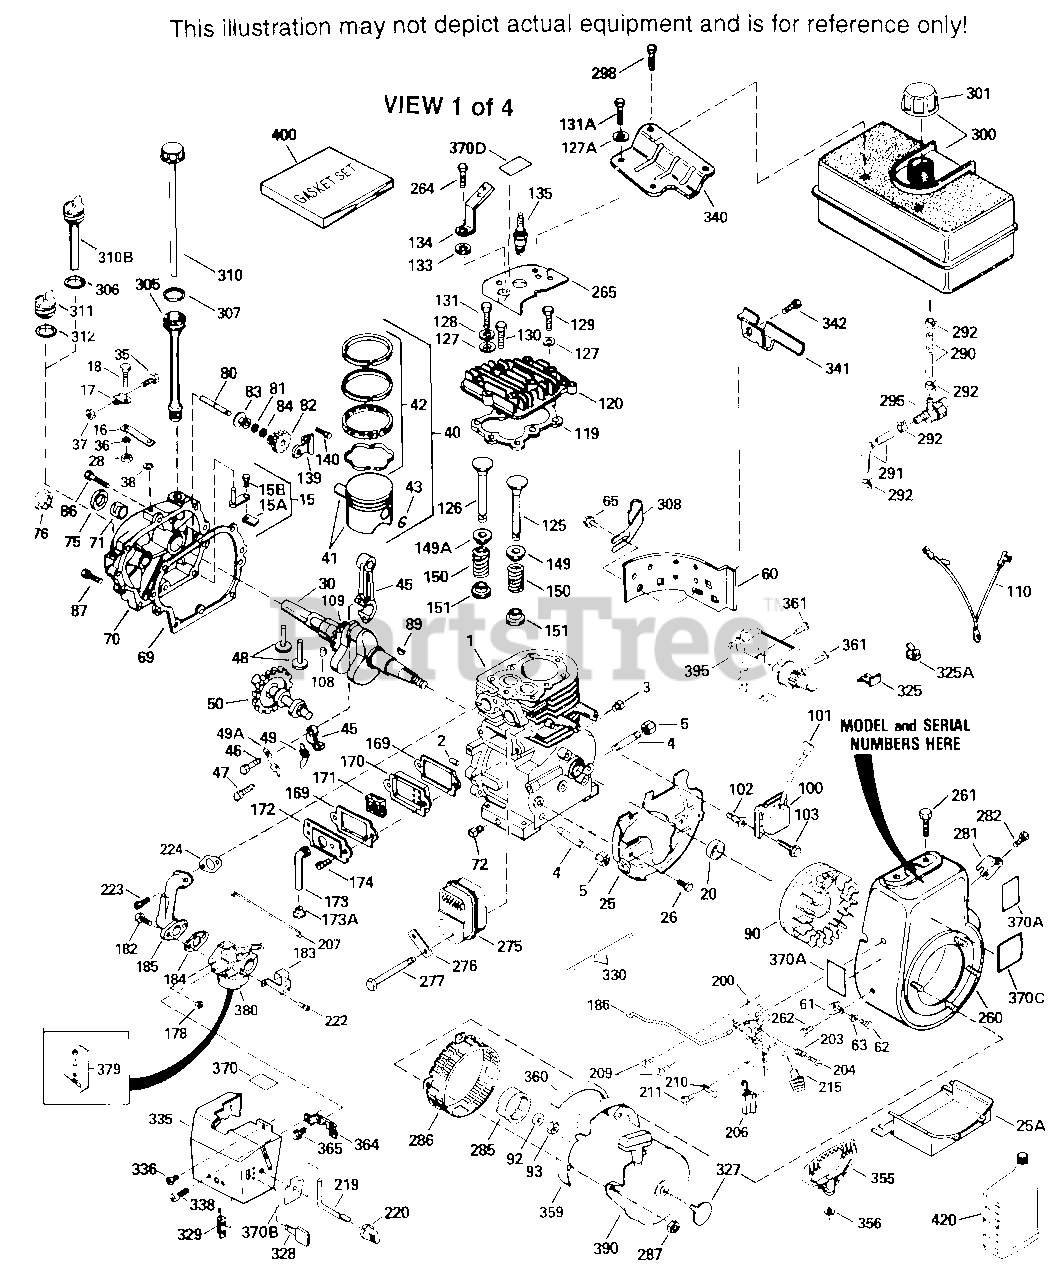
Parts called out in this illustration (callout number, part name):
1	"Cylinder (CI liner)(3-5/16")(Incl. 2, 20,41,43,72 & 119)
2	Dowel Pin
15	Rod Assy., Governor (Incl. 15A & 15B)
15A	Yoke, Governor
15B	Screw, 6-40 x 5/16"
16	Governor Lever Assy.
17	Governor Lever Clamp
18	Screw, 8-32 x 5/16"
20	Seal, Oil
25	Blower Housing Baffle (Without electr ic starter knockout) (Use as required )
25	Blower Housing Baffle (With electric starter knockout) (Use as required)
26	Screw, 1/4-20 x 5/8"
30	Crankshaft (Incl. 108 & 109)
35	Screw, 10-32 x 3/4"
36	Lock Washer #8
37	Lock Nut, 10-32
37A	Lock Nut, 8-32
38	Retaining Ring
40	Piston, Pin & Ring Set (Std.) 3-3/16 "
40	Piston, Pin & Ring Set (.010" OS)
40	Piston, Pin & Ring Set (.020" OS)
41	Piston & Pin Ass'y. (Std.)(3-3/16") I ncl. 43
41	Piston & Pin Ass'y. (.010" OS) Incl. 43
41	Piston & Pin Ass'y. (.020" OS) Incl. 43
42	Ring Set (Std.) (3-3/16" Bore)
42	Ring Set (.010" OS)
42	Ring Set (.020" OS)
43	Piston Pin Retaining Ring
45	Rod Assy., Connecting Incl. 46, 47 & 49
46	Bolt, Connecting rod (2 pieces)
47	Bolt, Connecting rod (2 pieces)
48	Lifter, Valve
49	Dipper, Oil
50	Camshaft (MCR)
60	Extension, Blower housing
62	Screw, 8-32 x 3/8"
63	Breather Tube Grommet
65	Screw, 10-24 x 1/2"
69	* Gasket, Flange
70	Cyl.Cover Incl. 71,75,80,179,180,220, 221
72	Oil Drain Plug (Sq. hd., 1/4-18)
75	Seal, Oil
80	Shaft, Mechanical governor
82	Gear Assy., Governor (Incl. 81)
83	Spool, Governor
84	Retaining Ring
86	Screw, 1/4-20 x 1-3/16 Use as requir ed
87	Screw, 1/4-20 x 1-11/16" Use as requi red
89	Key, Flywheel
92	Washer, Belleville
93	Nut, Hex
103	Screw, 1/4-20 x 5/8"
108	Pin, Crankshaft gear Only serviceable when gear is pinned to crank.
109	Gear, Crankshaft
110	Ground Wire (Incl. 156)
119	* Gasket, Cylinder head
120	Head, Cylinder
125	Exhaust Valve (Std.)(Incl. 151)
125	Exhaust Valve (1/32" OS) (Incl. 151)
126	Intake Valve (Std.) (Incl. 151)
126	Intake Valve (1/32" OS) (Incl. 151)
127	Washer Do not use with No. 6021A scr ew.
128	Washer, Belleville (Use as required)
129	Screw, 5/16-18 x 1-3/4 Use as requir ed
130	Screw, 5/16-18 x 1-1/2" Use as requir ed, but do notuse No. 650691 washer.
130	Screw, 5/16-18 x 2" (Use as required)
130	Screw, 5/16-18 x 1-5/8 " (Use as requ ired) (Can use 6021A but discard 6506 91 washer.)
131	Screw, 1/4-20 x 1/2" Use as required
131	Screw, 1/4-20 x 5/8 (Use as required)
133	Washer, Internal Lock
135	Resistor Spark Plug - RJ17LM
139	Bracket, Governor gear
140	Screw, 10-24 x 1/2"
149	Valve Spring Cap
150	Valve Spring
151	Cap, Lower valve spring
169	* Gasket, Breather
170	Breather Body
171	Breather Element
172	Valve Cover
173	Breather Tube
178	Nut & Lock Washer 1/4-28
182	Screw, 1/4-28 x 1"
184	* Gasket, Carburetor
185	Pipe, Intake
207	Link, Governor lever-to-throttle
222A	Pop Rivet (Can be purchased locally)
223	Screw, Torx T-30, 5/16-18 x 1-1/8"
224	* Gasket, Intake pipe
241	Bracket, Air cleaner
260	Blower Housing (For electric starter)
261	Screw, 5/16-18 x 3/4"
262	Screw, T-40, 5/16-24 x 21/32"
265	Cover, Cylinder head
276	Locking Plate
277	Screw, 5/16-18 x 3-3/16" Use as requi red
277	Screw, 5/16-18 x 4-1/4" Use as requir ed
281	Cover, Starter bubble
282	Screw, 8-32 x 7/16"
290	Fuel Line (8.62") equired)
290	Fuel Line (Braided 32")(80cm) As requ ired
291	Fuel Line (Braided 16")(40cm) As requ ired
292	Fuel Line Clamp
306	* Gasket, Oil filler
310	Dipstick (Incl. 307)
310B	Dipstick (Incl. 306)
311	Oil Fill Plug (Incl. 312) also availa ble in Packaged Part #740079
312	* Gasket, Oil filler plug
338A	Plug, Cover
342	Screw, T-30, 1/4-20 x 1/2"
370	Decal, Instruction
370	Decal - Important Lubrication - SAE 3
370A	Decal, Name
379	Inlet Needle, Seat & Clip Assy.
380	Carburetor (Incl. 184 & 379) (Refer t o Division 5, Section A, page A3-6 fo r breakdown or Fiche 18B, Grid E-5)
400	* Gasket Set (Incl. items marked *)
420	SAE 30 4-Cycle Engine Oil (Quart)
421	SAE 5W30 4-Cycle Engine Oil - Quart - Winter
422	Muffler Optional
